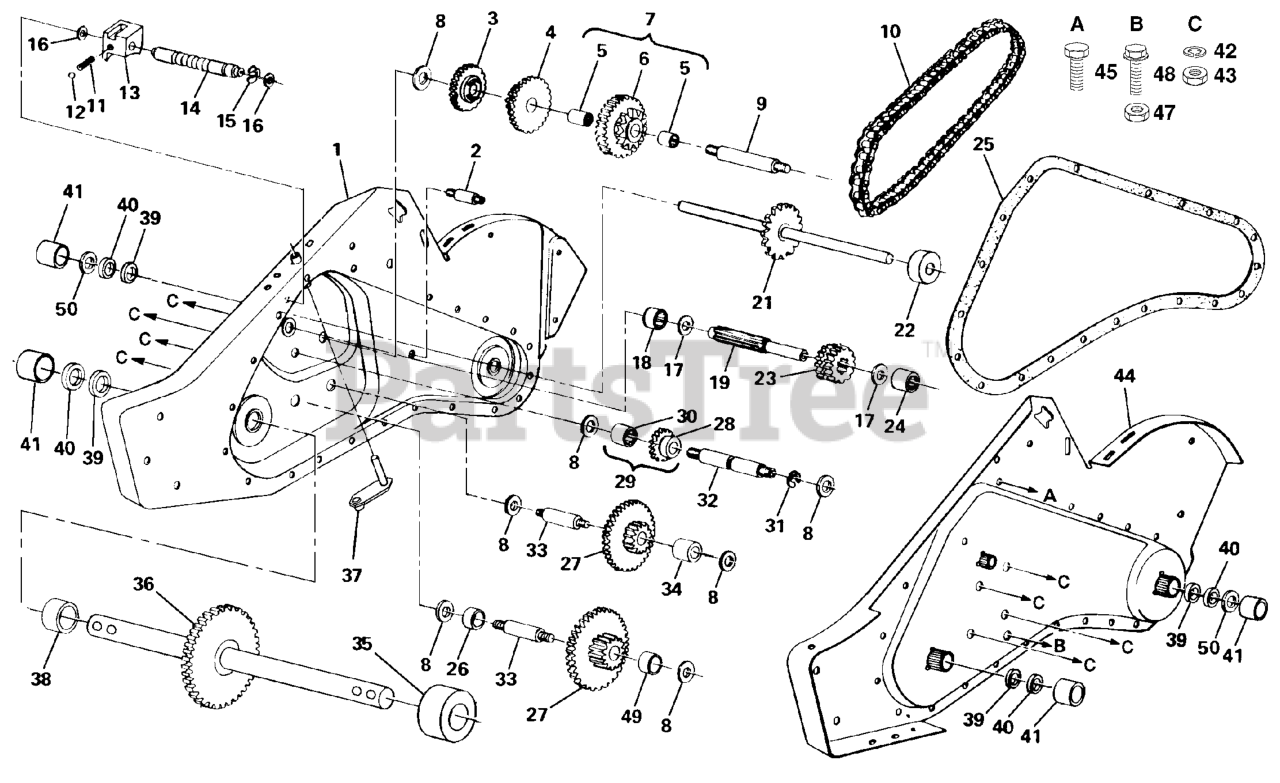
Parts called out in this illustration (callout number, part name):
1	GEARCASE ASSY RH
3	GEAR, REVERSE
4	GEAR, CLUSTER (2 GEAR SET)
5	BEARING.NEEDLE.CRT
6	SPROCKET ASMBLY, TINE
7	SPROCKET ASMBLY W/BEARINGS
9	SHAFT.REDUCTION.TILLER
10	CHAIN.ROLLER.TILLER
11	SPRING-SHIFT CRT
12	STEEL BALL KIT
13	SHIFT FORK TI
14	SHAFT, SHIFT
16	Washer, Seal
17	THRUST WASHER
18	BEARING TI
19	SHAFT INPUT
21	SHAFT TINE CRT
22	SPACER 1.008X1-3/4X.645
23	PINION, INPUT
24	NEEDLE BRNG LT
25	GASKET, GEARCASE
27	GEAR, CLUSTER CRT
28	REVERSE GEAR
29	GEAR ASMBLY, REVERSE IDLER
30	NEEDLE BEARING TI
32	SHAFT, REVERSE IDLER
33	SHAFT, REDUCTION
34	SPACER.765 X 1.12 X .380.
35	SPACER, GROUND DRIVE RH
36	SHAFT ASSY CRT
37	BRACKET ASM.SHIFT.CRT
38	SPACER, GROUND DRIVE
39	OIL SEAL STD
41	CUP
42	LOCKWASHER
43	NUT.ASF.HEX.7/16
44	GEARCASE ASSY LH
45	SCREW
47	NUT
48	SCREW 5/16-18X4
50	RING.SPIRAL.CRT.TILLER
